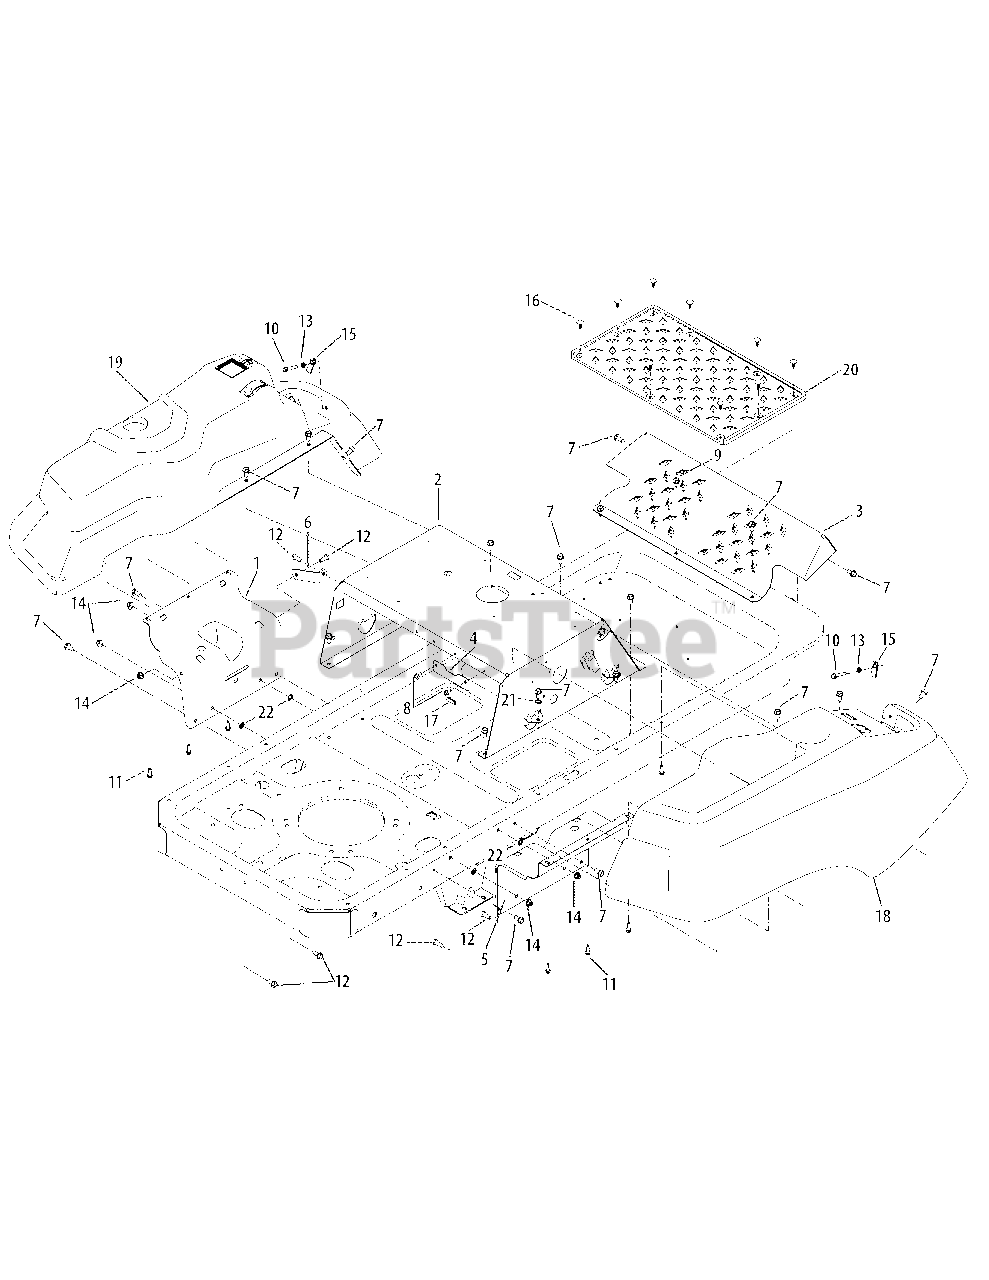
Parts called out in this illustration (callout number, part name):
1	Console Bracket Assembly
2	Seat Frame Assembly (NLA)
2	Seat Frame Assembly)
3	Foot Rest Bracket
4	Battery Hold-Down Bracket
5	Console Mount Bracket
6	Fuel Tank Support Bracket
7	Hex Washer Screw, 5/16-18 x .750
8	Hex Washer Screw, 1/4-20 x .500
9	Hex Washer Screw, 5/16-18 x .625
10	Hex Washer Screw, 1/4-20 x 1.500
11	Hex Washer Screw, 1/4-15 x .750
12	Hex Screw, 5/16-18 x .75
13	Jam Nut, 1/4-20
14	Flange Lock Nut, 5/16-18
15	Speed Nut, 1/4-20
16	Ratchet Clip
17	Trim Strip
18	RH Console
19	LH Console
20	Foot Pad
21	Lock Washer, 3/8
22	Speed Nut, .3125
